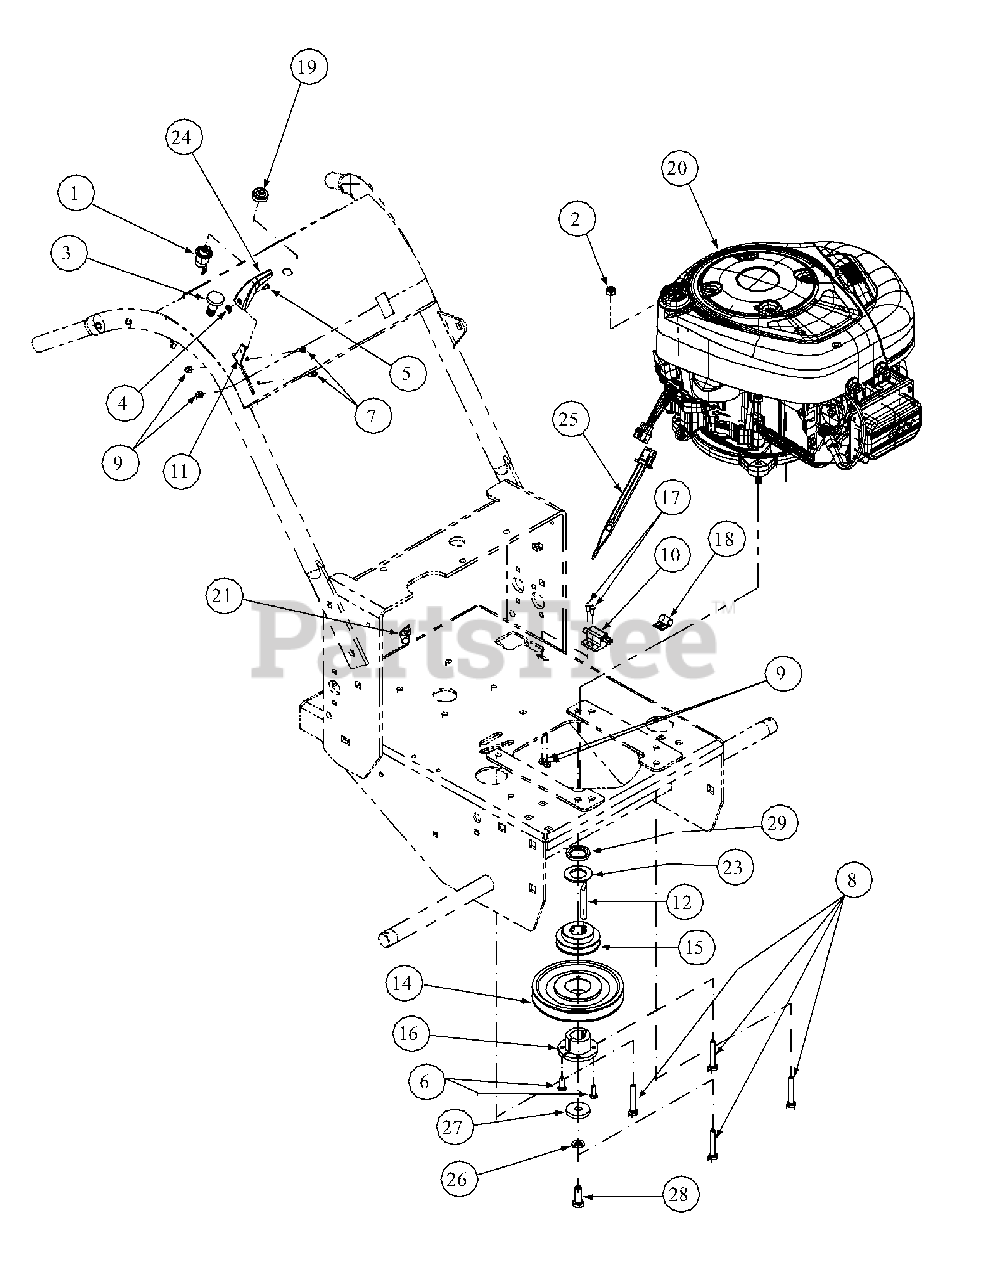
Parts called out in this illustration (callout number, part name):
1	Single Ignition ON/OFF Switch
2	Nut, 5/16-18, Nylock
3	Choke Cable
4	Nut, 8-32, w/Star Washer
5	Screw, 8-32 x 0.375
6	Hex Cap Screw, 1/4-20 x 0.75
7	Screw, Hex Washer, 10-32 x 1/2
8	Hex Cap Screw, 5/16-18 x 2.00
9	Lock Nut, Nylon Insert, 10-32
10	Delta Switch
11	Throttle Cable
12	Key Stick, 1/4 x 1/4 x 2-3/4
13	Harness Wire
14	Deck Pulley
15	Traction Pulley
16	Bushing
17	Machine Screw, 10-32 x 5/8
18	Support Clamp Tubing, 1/2"
19	Nut w/cap, 5/8-32 Ignition
21	Support Clamp, 3/8 OD
22	Belt
23	Flat Washer
24	Throttle Control Knob
25	Harness Adaptor
26	Lock Washer, 7/16
27	Clutch Washer
28	Hex Cap Screw, M10 x 1.5, 30mm, GR10.9
29	Spacer, Engine Pulley
